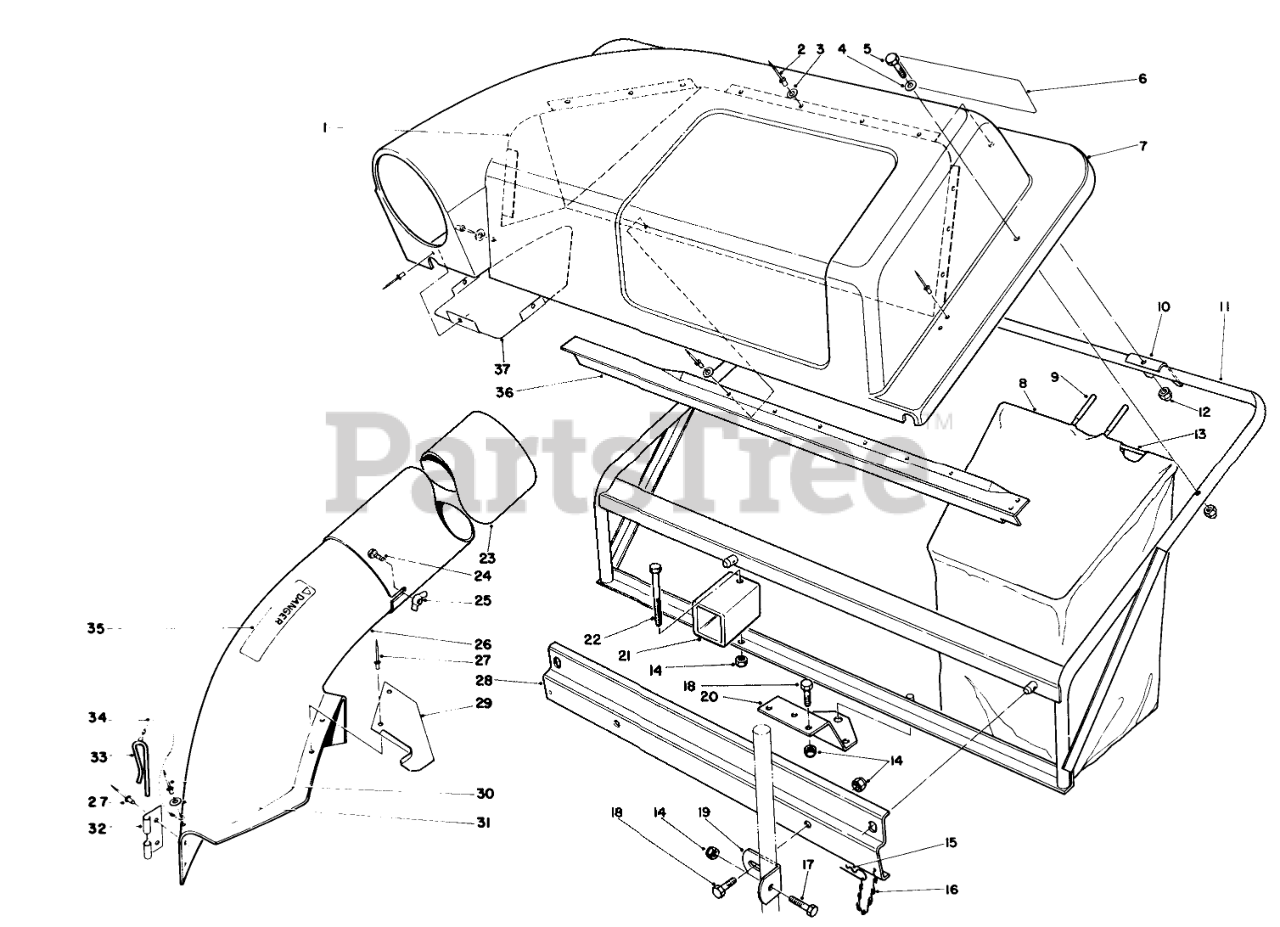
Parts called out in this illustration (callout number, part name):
1	Screen Cover
3	WASHER-FLAT
4	WASHER-PLAIN
5	SCREW-HH
6	Decal-Twin Bagger
7	Cover
8	Bag-Twin Bagger (Incl. Ref. #9 & 13)
9	GRIP-HANDLE, BAG
10	BAG FRAME BRKT
11	Frame
12	NUT-LOCK, CAP
13	Frame-Bag
14	NUT-LOCK, CONE
15	PIN-HAIR
16	6-LINK CHAIN W/HOOK
17	SCREW-HH
18	SCREW-HH
19	Bracket Mtg. Grass Catcher
20	MTG PLATE B
21	FRAME SUPT TUBE B
22	SCREW-HH
23	TUBE(ROUND&LONG)
24	BOLT-CARR
25	NUT-WING SPECL
26	Chute Assembly (Incl. Ref. #27, 29-35)
27	Rivet
28	Bracket Frame Support
29	CHUTE SUPT BRKT
30	RIVET-BLIND
31	WASHER-PLAIN
32	BRACKET-MOUNTING, CHUTE
33	PIN-LOCKING, CHUTE
34	LANYARD
35	Decal-Chute
36	SCREEN SUPT BRKT B
37	Shield Cover
